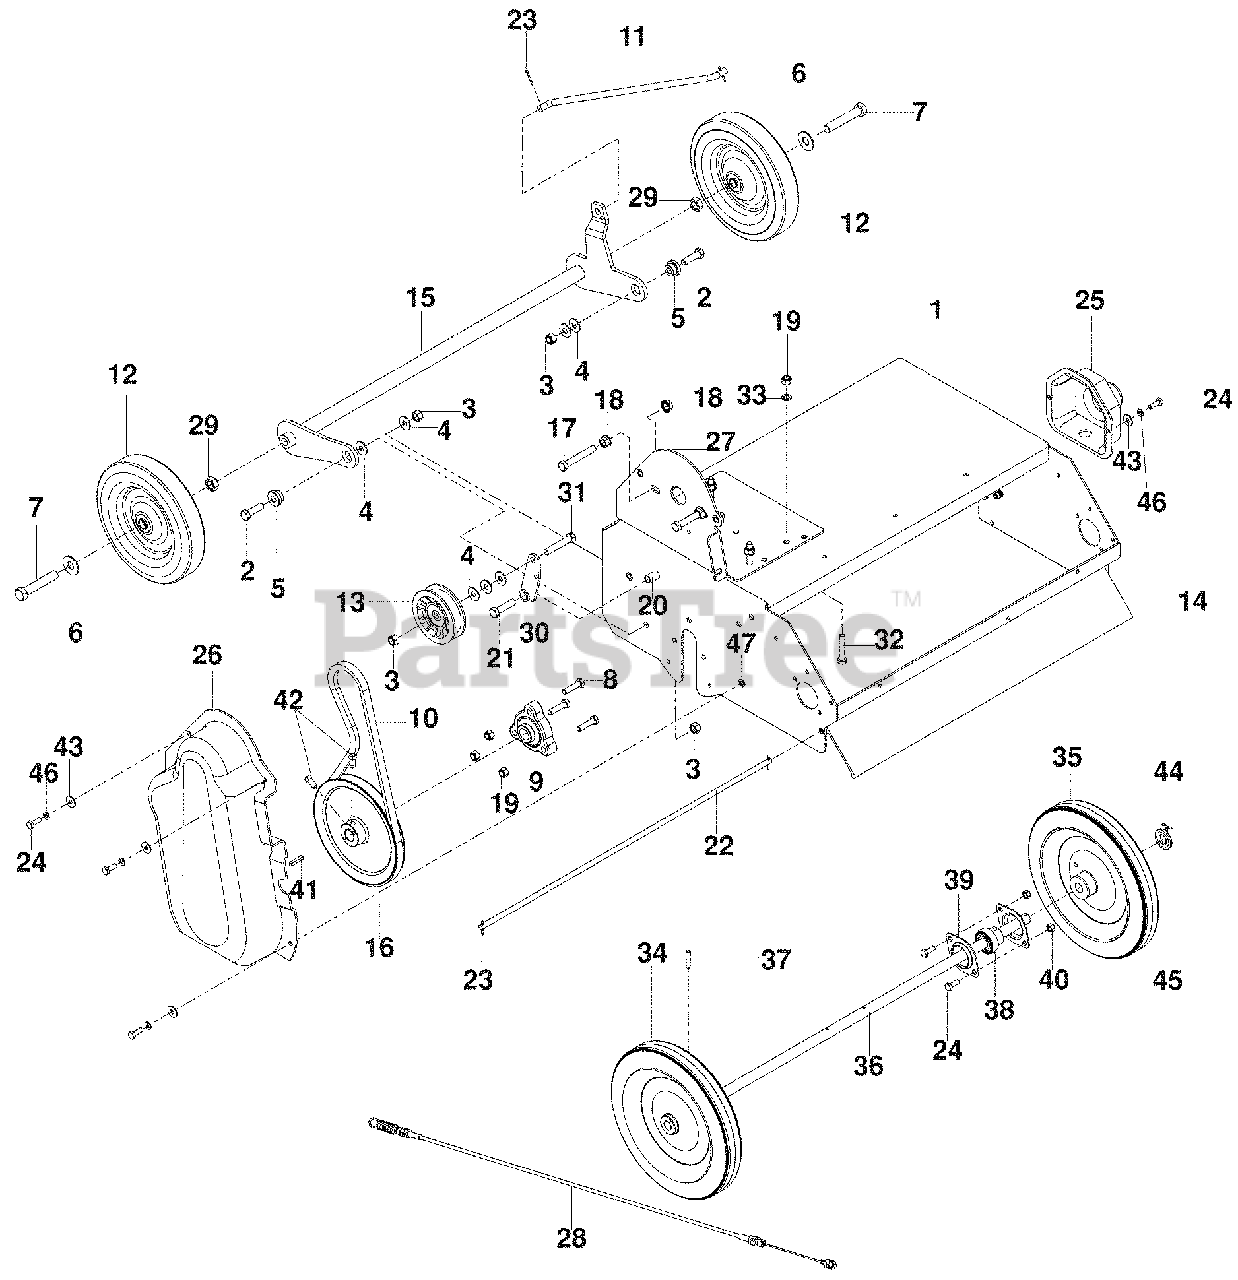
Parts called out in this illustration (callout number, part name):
1	BODY
2	HCS 3/8-16 x 1¼
3	NUT 3/8-16 NYLOC
4	WASHER 5/16
6	WASHER, ½
7	HCS ½-13 x 2¾
8	HCS 5/16-18 x 1¼
9	BEARING FLANGE C.I.
12	WHEEL, 8 x 1.75
13	IDLER PULLEY, HYDRO'S
15	AXLE, FRONT
16	PULLEY, 7"
17	HCS 3/8-16 x 2½
18	NUT 3/8-16 WHIZLK
19	NUT 5/16-18 NYLOC
21	HCS 3/8-16 x 1½
23	PIN COTTER ¾
24	HCS ¼-20 x ¾
25	SHAFT GUARD
26	BELT GUARD
27	BACKING PLATE
29	NUT ½-13 JAM
30	IDLER, ARM
31	HCS 3/8-16 x 2
32	HCS 5/16-18 x 1¾
33	LOCKWASHER 5/16
34	WHEEL, 10x1.75 DRILLED
35	WHEEL, 10x1.75 w/ BUSHING
37	PIN ROLL ¼ x 11/8
38	BEARING 5/8 w/ COLLAR
39	BRG FLANGETTE 5/8 2 BOLT
40	NUT ¼-20, NYLOC
41	KEY ¼ SQ x 11/8
42	SCREW 5/16-18 x 5/8 SET
43	WASHER ¼
44	COTTER PIN 1/8 x 1½
45	WASHER 5/8 SAE
46	WASHER ¼ SPLIT LOCK
47	KNURLED INSERT ¼-20
